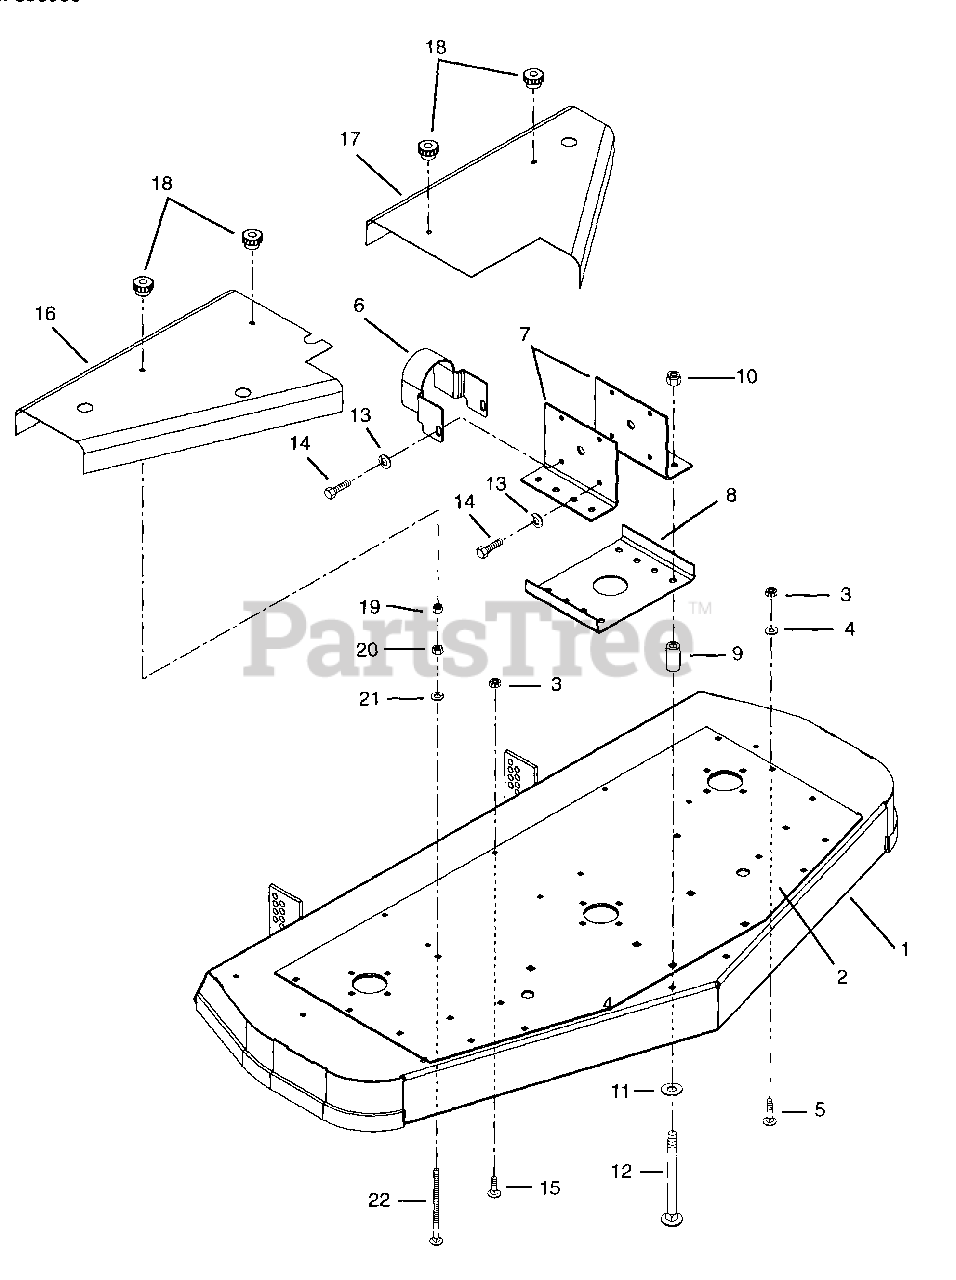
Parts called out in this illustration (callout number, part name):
1	Weldment, 60" Rear Discharge Deck
2	Plate, 60" Deck Reinforcement
3	Nut-Locking-Nylon .375-16 Grade 2
4	Washer-Flat-Steel .406 x .812 x .065
5	Bolt-Round Head Square Neck .38-16 x 1.0
6	Shield, U-Joint
7	Bracket, Gearbox Mounting
8	Plate, Support
9	Spacer .562 x 1.00 x 2.00
10	Nut-Locking-Nylon .50-13 Grade 5
11	Washer-Flat-Steel .531 x 1.062 x .095
12	Bolt-Hex .50-13 x 3.75
13	Washer-Lock .375 x .094
14	Bolt-Hex .380-16 x .875
15	Bolt-Round Head Square Neck .31-18 x .62
16	Cover, Mower Belt Right Hand
17	Cover, Mower Belt Left Hand
18	Knob
19	Nut-Locking-Nylon .312-18 Grade 2
20	Nut-Hex .312-18 Grade 2
21	Washer-Lock .313 x .078
22	Bolt-Round Head Square Neck .31-18 x 3.50
